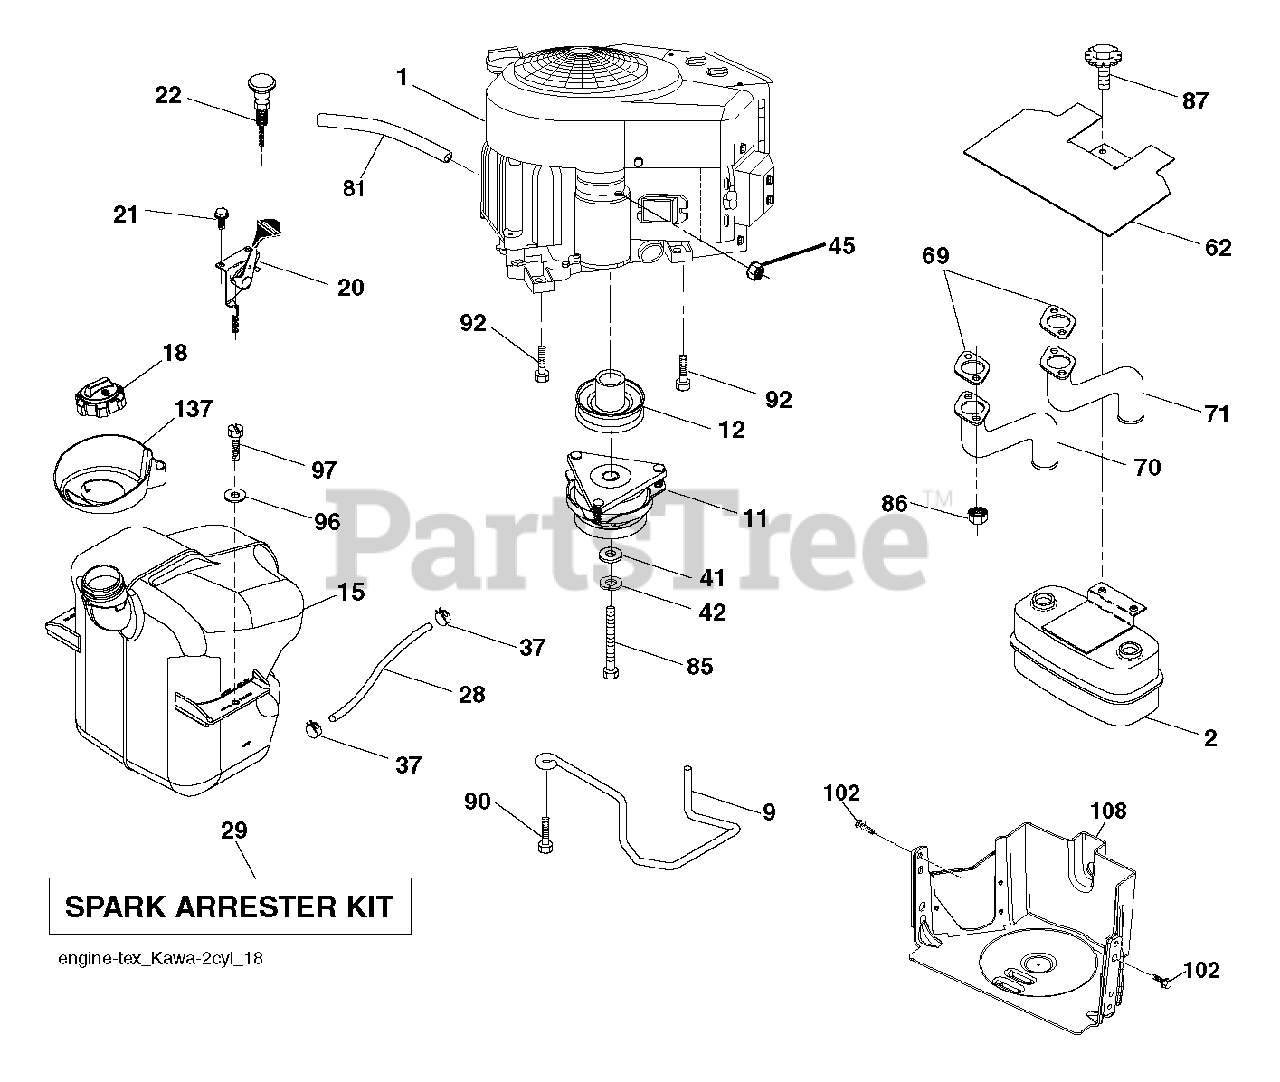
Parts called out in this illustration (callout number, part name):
2	MUFFLER.TWIN.CYL.LOW.TONE
9	KEEPER.BELT.ENGINE.4.2
11	CLUTCH.ELECTRIC.LT.48"*
12	PULLEY.ENGINE.TUFFTORQ
15	FUEL TANK TANK. ASSEMBLY. EXTE
18	CAP.ASM.FUEL.2.25"TOP.TURN
20	CONTROL.THROTTLE.COBRA.BLACK
21	SCREW.#10 X 0.750.BOS
22	CONTROL.CHOKE.ERGO.PUSH-IN.BLA
28	LINE.FUEL.20
29	KIT.SPARK ARRESTOR 794945 B&S
37	HOSE CLAMP
42	LOCKWASHER
45	NUT
62	SHIELD.HEAT.MUFFLER
70	TUBE.EXHAUST.LH.FR961/FR730
71	TUBE.EXHAUST.RH.FR961/FR730
81	TUBE, DRAIN OIL ASM.
85	BOLT HEX 7/16-20X4-1/4"
86	NUT.HEX.FLANGE.TOPLOCK
87	Bolt, 5/16-18 X 1-3/4
90	SCREW 3/8-16X1
92	SCREW 3/8-16X1
97	SCREW HEXWSHR 1/4-20X3/4
102	SCREW 5/16-18X1
108	COVER PULLEY
